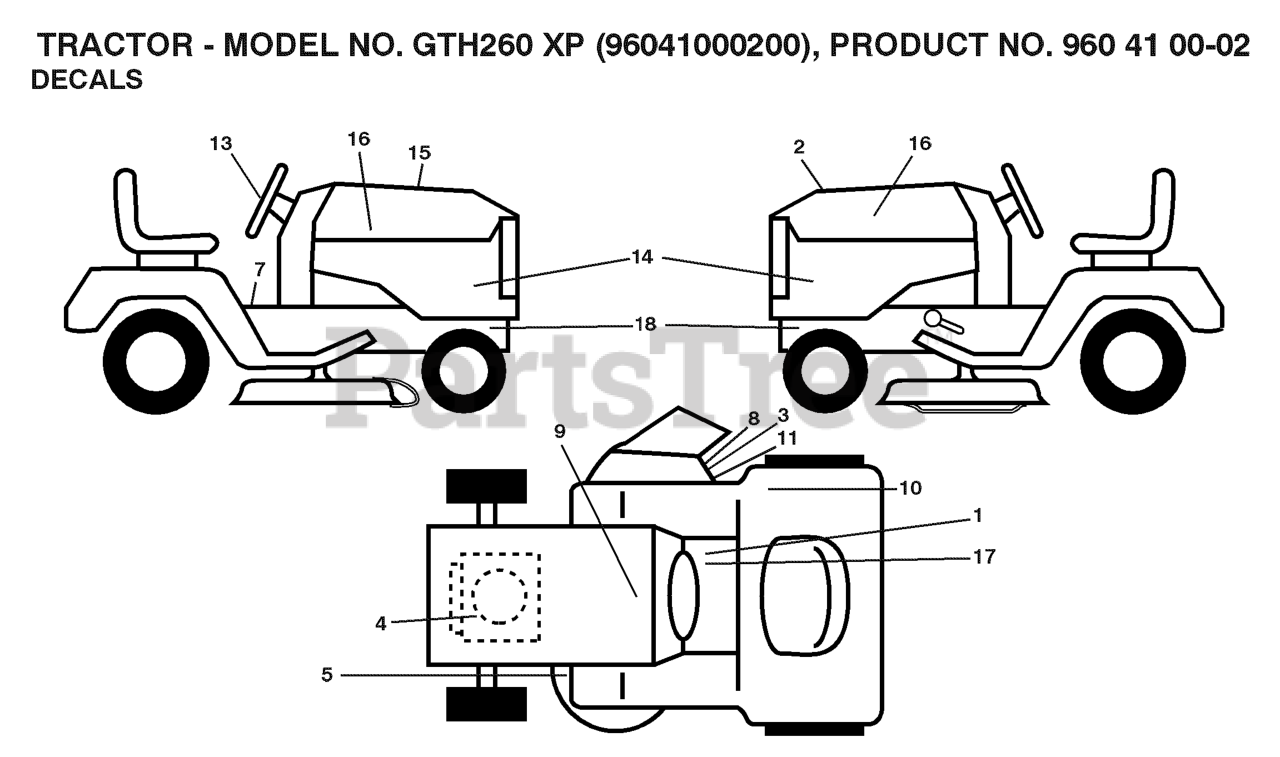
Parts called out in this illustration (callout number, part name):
1	DECAL
2	DECAL.HOOD.TOP.INSERT.
3	DECAL, DEFLECT WARNING
4	DECAL
5	DECAL
7	LABEL
8	DECAL.MOWER.SCH.48/54
9	DECAL BTRY SYMBOLS
10	DECAL.FENDER
11	DECAL.INTERNATIONL.CUTFINGER
13	DECAL.STEERING.HUSQ.BLUE
16	DECAL.HOOD.NAMELOGO.HUSQ
17	DECAL PARK BRAKE
